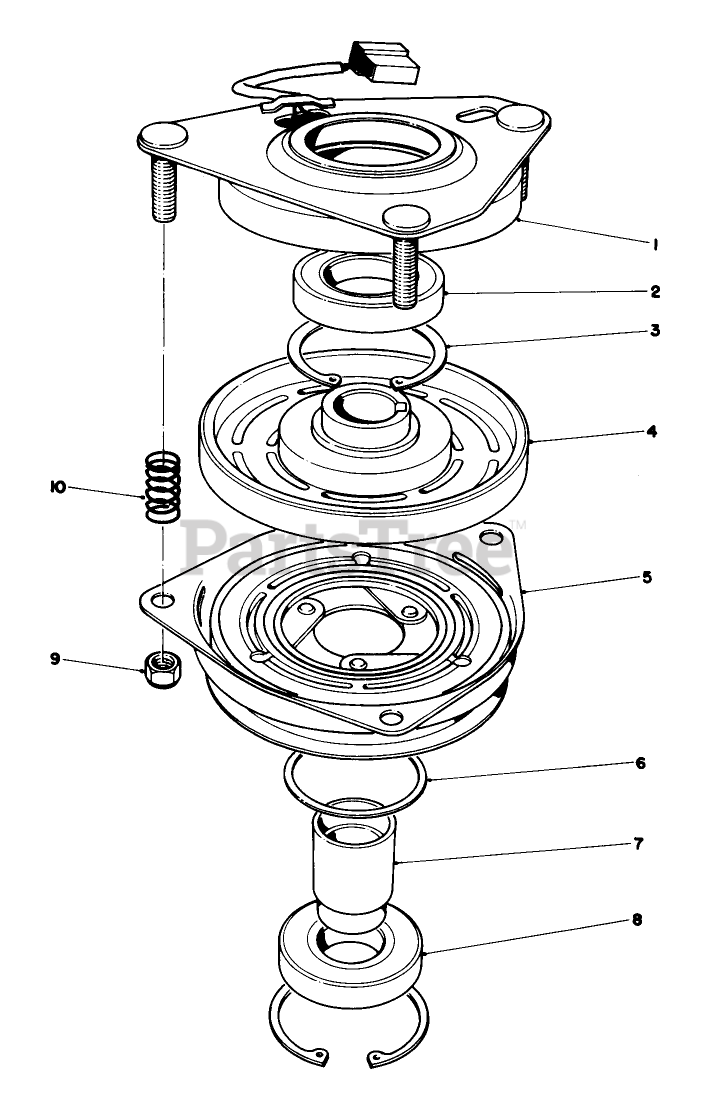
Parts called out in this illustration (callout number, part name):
1	Field Assy. (Incl. Ret. #2 & 3)
2	BEARING-FIELD
3	RING-RETAINING
4	Field Coil, Rotor& Bearing Assembly (Incl. Ref. # 1)
5	Armature & Pulley Assembly (Incl. Ref.#3,6,7&8)
6	SPACER-BEARING, PULLEY
7	COLLAR-BEARING
8	BEARING-PULLEY
9	NUT-LOCK
10	SPRING
